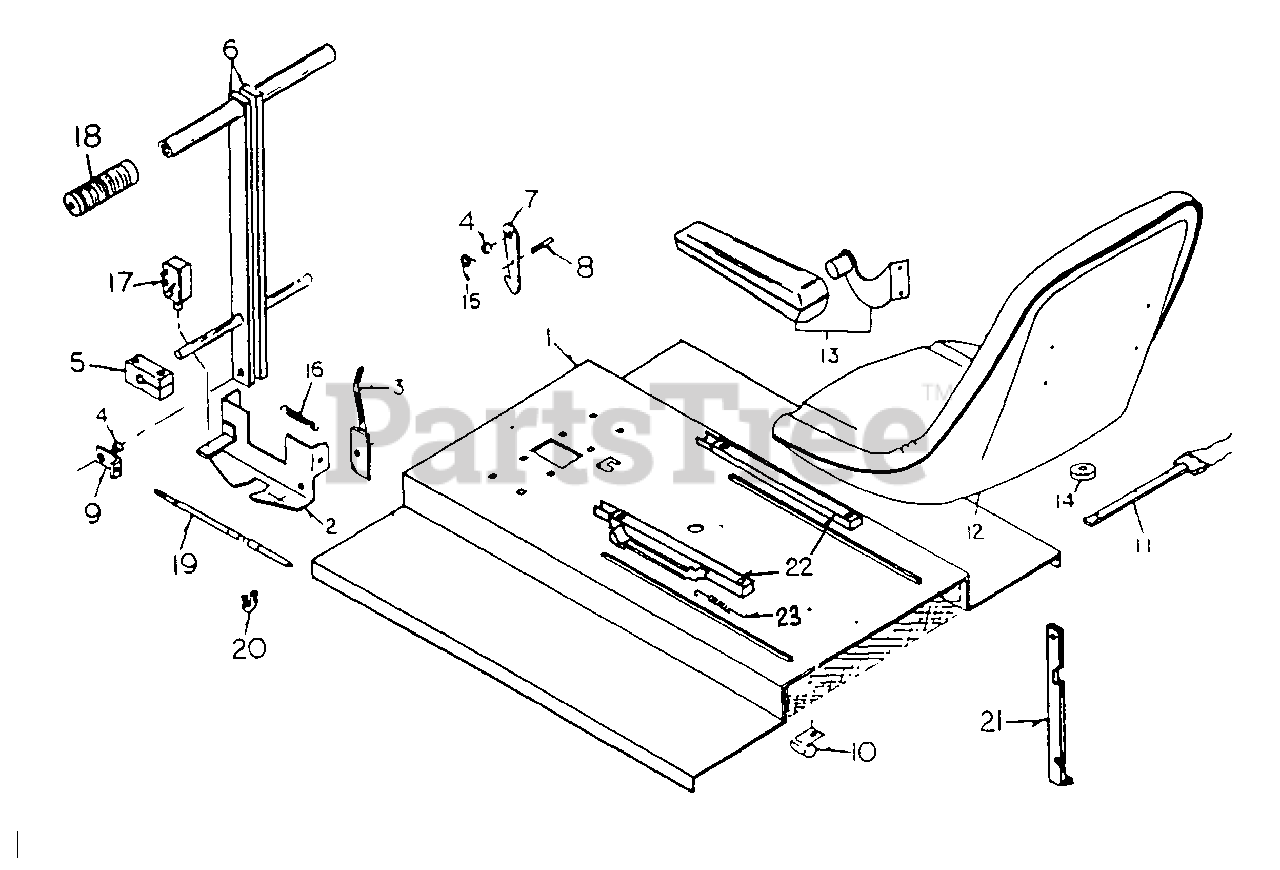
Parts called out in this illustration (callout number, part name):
3	Latch, Lever Lock
4	Bushing
6	Steering Lever
7	Seat Lid Latch
8	Seat Lid Latch Bolt
9	Steering Cable End
10	Seat Lid Harness Retainer
13	Arm Rest Kit
15	Seat Lid Latch Spring
16	Lever Lock Spring
18	Handle Grip
19	Steering Cable
20	Steering Cable Clamp
22	Seat Rail Kit (Pair)
